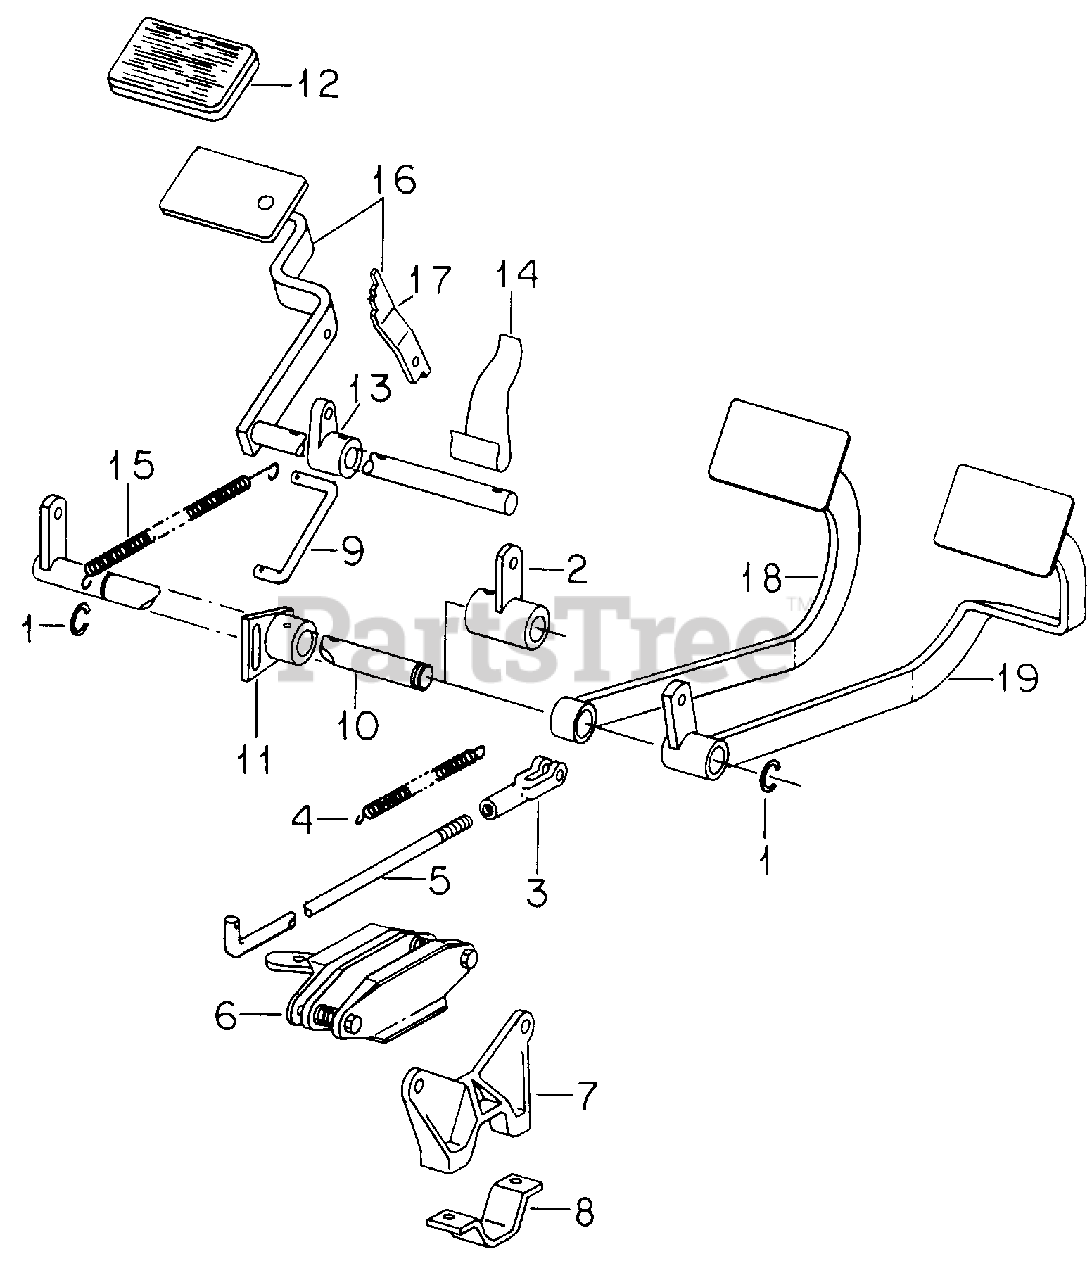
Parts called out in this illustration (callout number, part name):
1	Ring Retaining
2	Lever Assy, RH Brake
3	Clevis, 3/8 X 24 Adj Rod End
4	Spring Brake Return
5	Rod Brake
6	Brake Assembly
7	Bracket, Caliper Mtg
8	Flange Caliper Mounting
9	Rod, Center Brake
10	Shaft Assy, Brake
11	Arm Assy, Parking Brake Plate
12	Pad, Pedal
15	Spring, Return
16	Pedal Assy, Neutral Return & Brake
17	Ratchet
